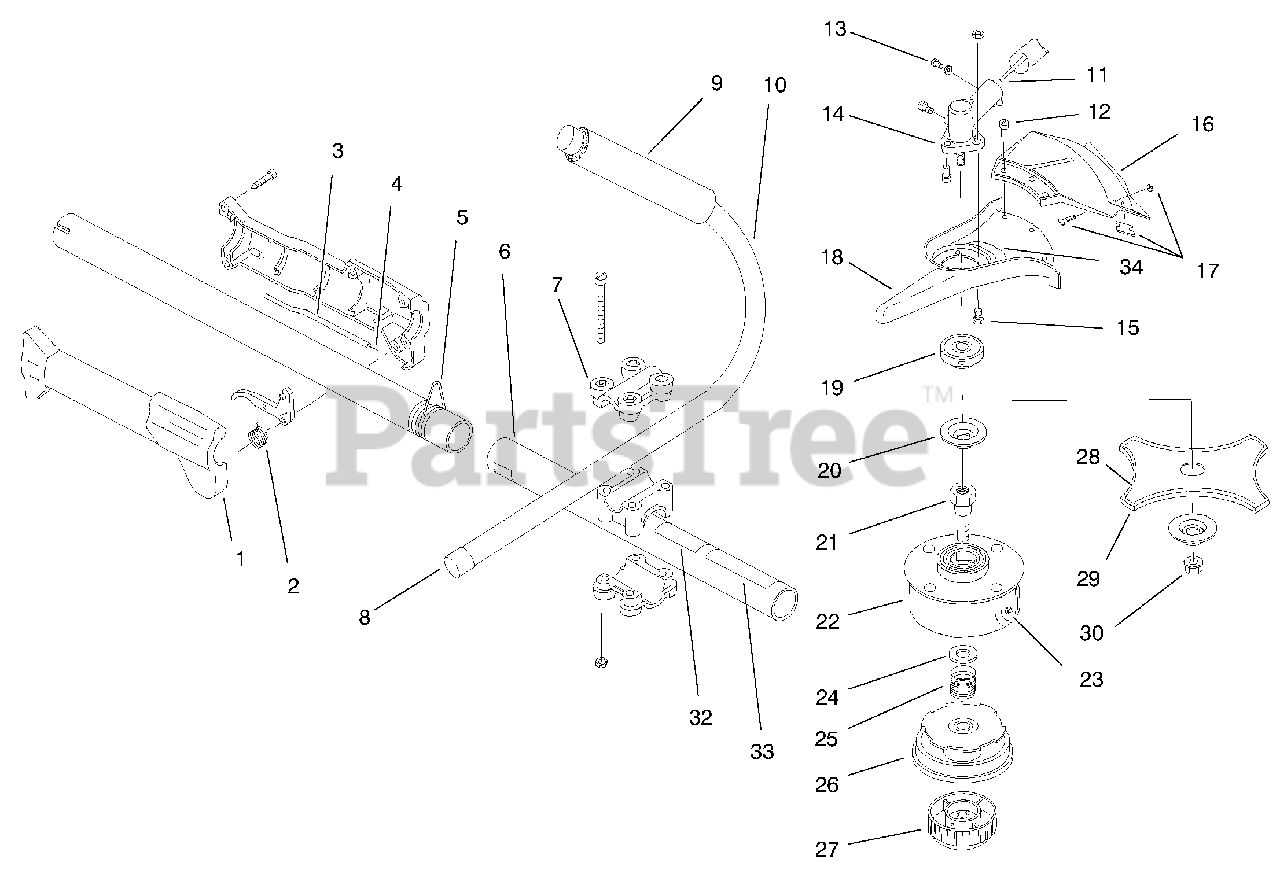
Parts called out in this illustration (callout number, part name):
1	Throttle & Trigger Asm.
2	Throttle Trigger Spring
3	Throttle Cable Housing
4	Throttle Cable
5	Shoulder Strap Clamp
6	Drive Shaft Housing Asm.
7	Handle Bracket Asm.
8	Tube Closure
10	J-Handle Asm. (Incl. Ref. #8-9)
11	Flexible Drive Shaft
12	Guard Mounting Screws
13	Mounting Hardware & Grease Plug Asm.
14	Gear Box Asm. (Incl. Ref. #13, 19, 20, 30)
15	Guard Mounting Screws
16	Guard and Blade Asm. (Incl. Ref. #17)
17	Blade Asm.
18	Guard Mount
19	Blade Drive
20	Blade Retaining Washer
21	Spool Shaft
22	Outer Spool & Eyelet Asm.
24	Retainer
26	Inner Reel
27	Bump Head Knob Asm.
28	Blade
29	Blade Cover
30	Lock Nut
32	Decal-Safety Symbols
33	Decal-Safety
34	Decal-Warning
